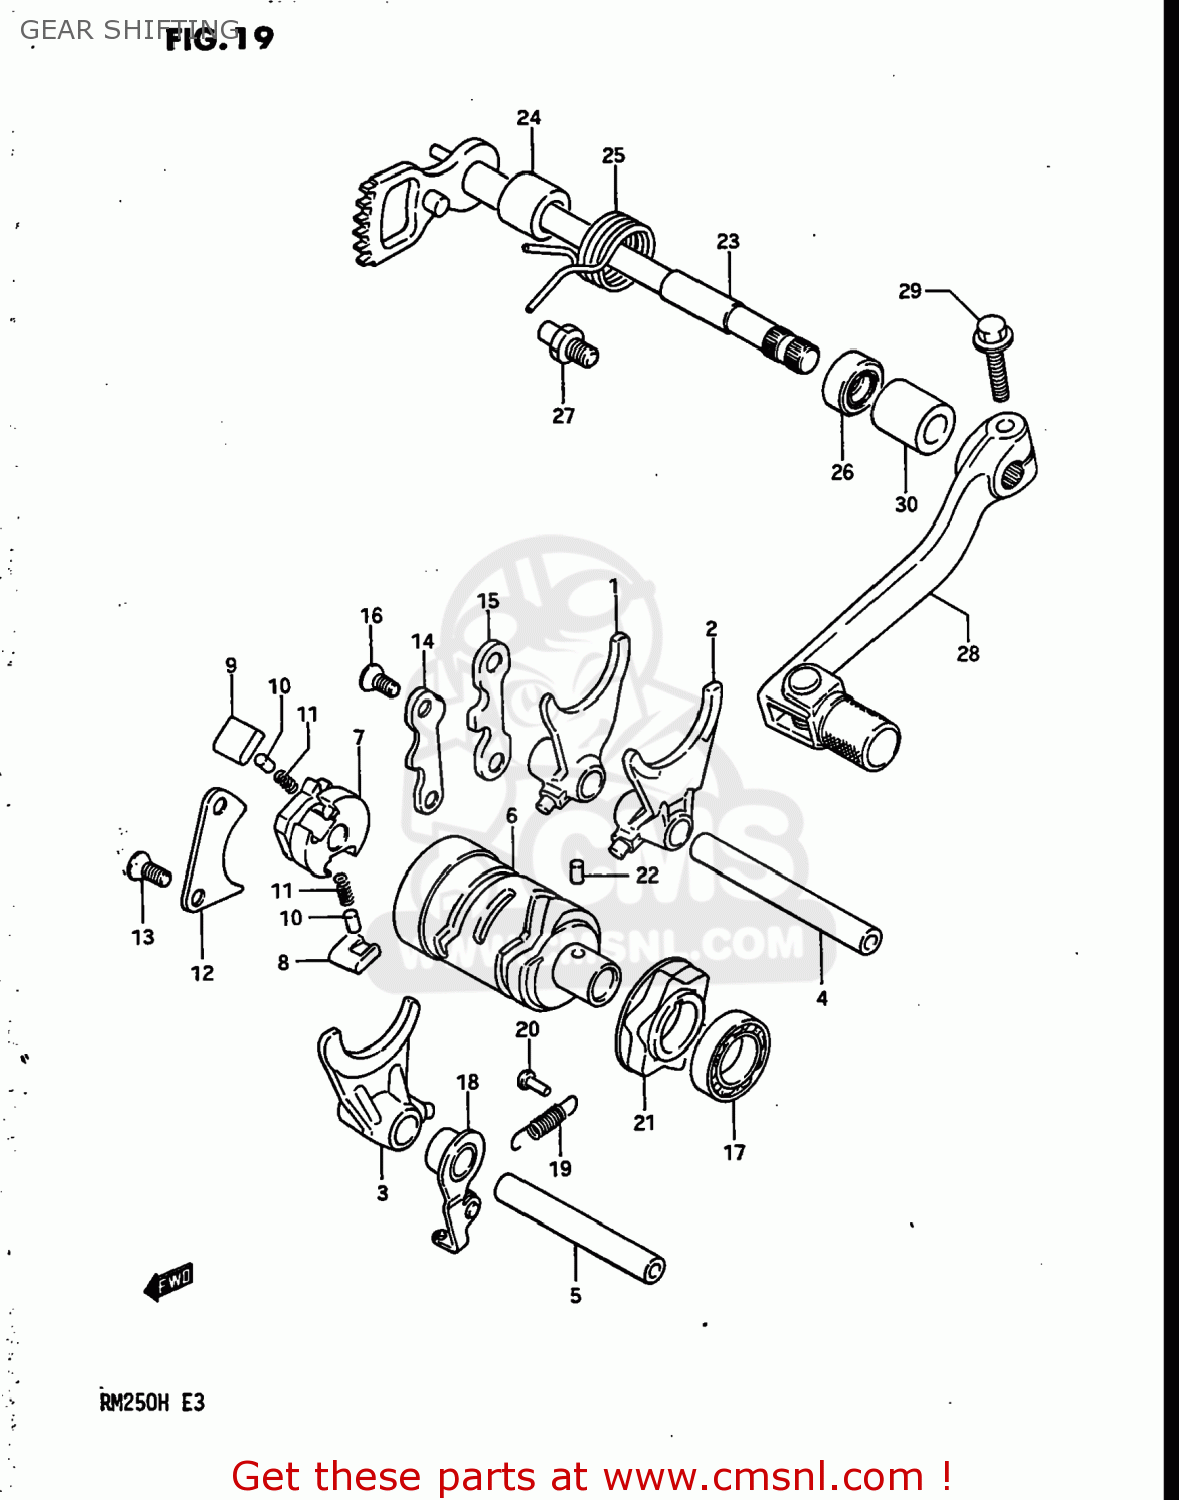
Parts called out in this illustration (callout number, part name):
1	FORK,GEAR SHIFT NO.1
2	FORK,GEAR SHIFT NO.2
3	FORK,GEAR SHIFT NO.3
4	SHAFT,GEAR SHIFT FORK
5	SHAFT,GEAR SHIFT FORK NO.2
6	CAM,GEAR SHIFT
7	GEAR,GEARSHIFT CAM DRIVE
8	PAWL,GEAR SHIFT NO.1
9	PAWL,GEAR SHIFT NO.2
10	PIN(5X8)
11	SPRING
12	LIFTER,GEAR SHIFT PAWL
13	SCREW
14	GUIDE,GEAR SHIFTING CABLE
15	GUIDE,GEAR SHIFT CAM
16	SCREW
17	BEARING
18	STOPPER,GEAR SHIFTING CAM
19	SPRING
20	RIVET
21	PLATE,GEAR SHIFT CAM STOPPER
22	PIN
23	SHAFT COMP,GEAR SHIFTING
24	SPACER(12X20X15.3)
25	SPRING
26	OIL SEAL
27	STOPPER,GEAR SHIFT CAM
28	LEVER ASSEMBLY,GEAR SHIFTING
29	BOLT
30	CUSHION 12X20X20
